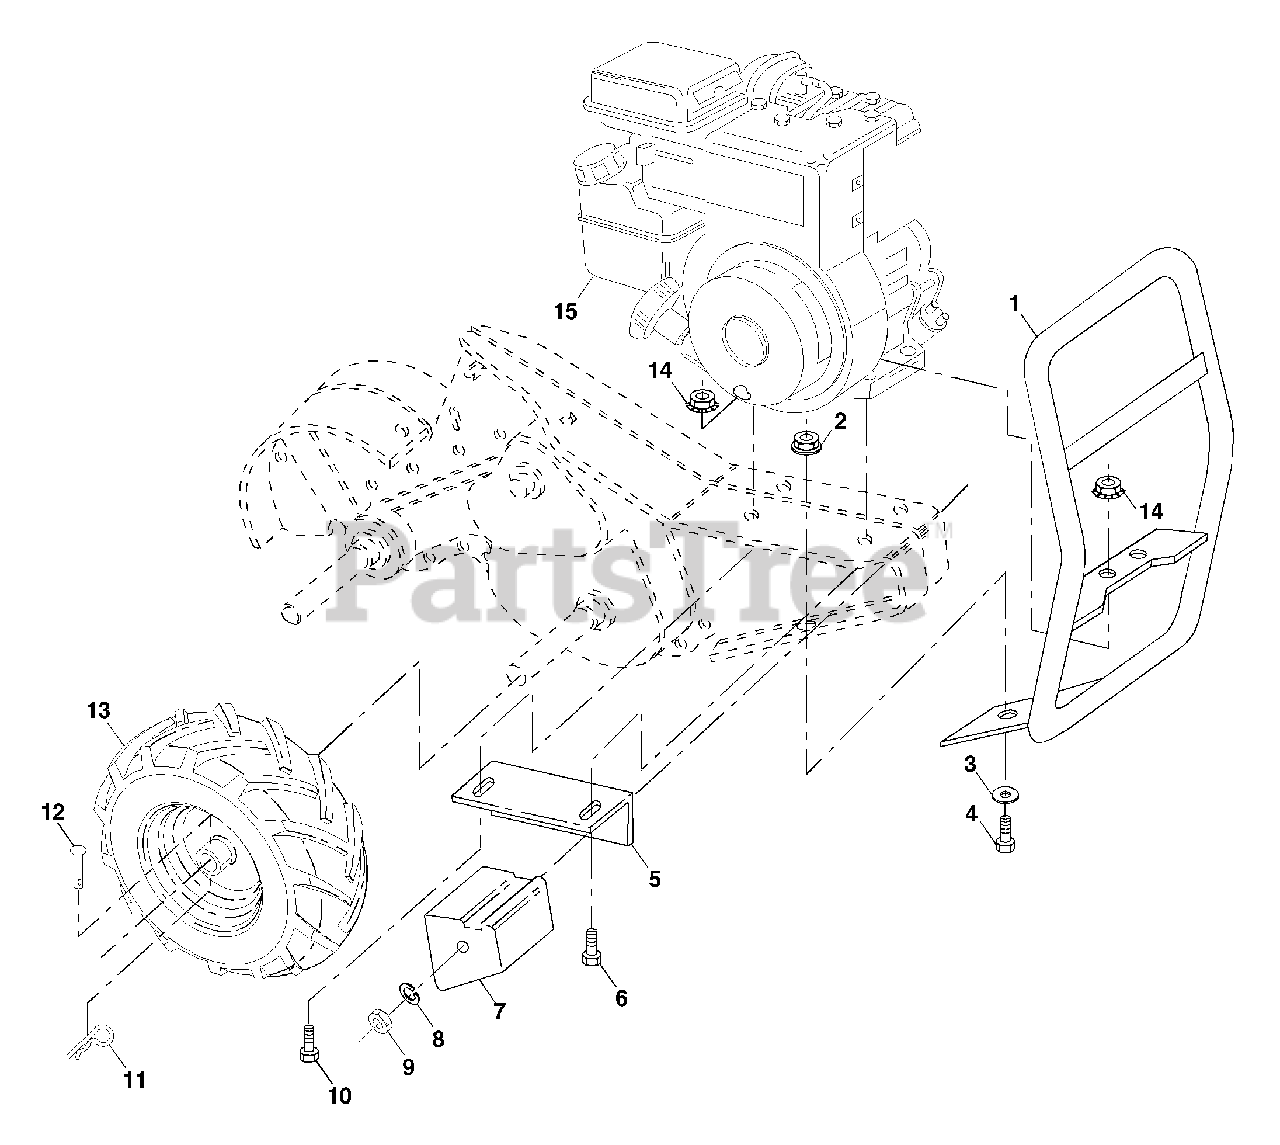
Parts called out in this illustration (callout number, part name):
2	Locknut, Hex, Flange 5/16-18
3	Washer 11/32 x 11/16 x 16 Ga.
4	Bolt, Hex 5/16-18 x 3/4
5	Bracket, Reinforcement
6	Bolt, Hex 5/16-18 x 2
7	Counter Weight, R.H.
8	Washer, Lock 3/8
9	Nut, Hex 3/8-16
10	Bolt, Hex 5/16-18 x 1-1/2
11	Clip, Hairpin
12	Rivet, Drilled
13	Rim
13	Tire Valve
14	Nut, Keps 5/16-18
